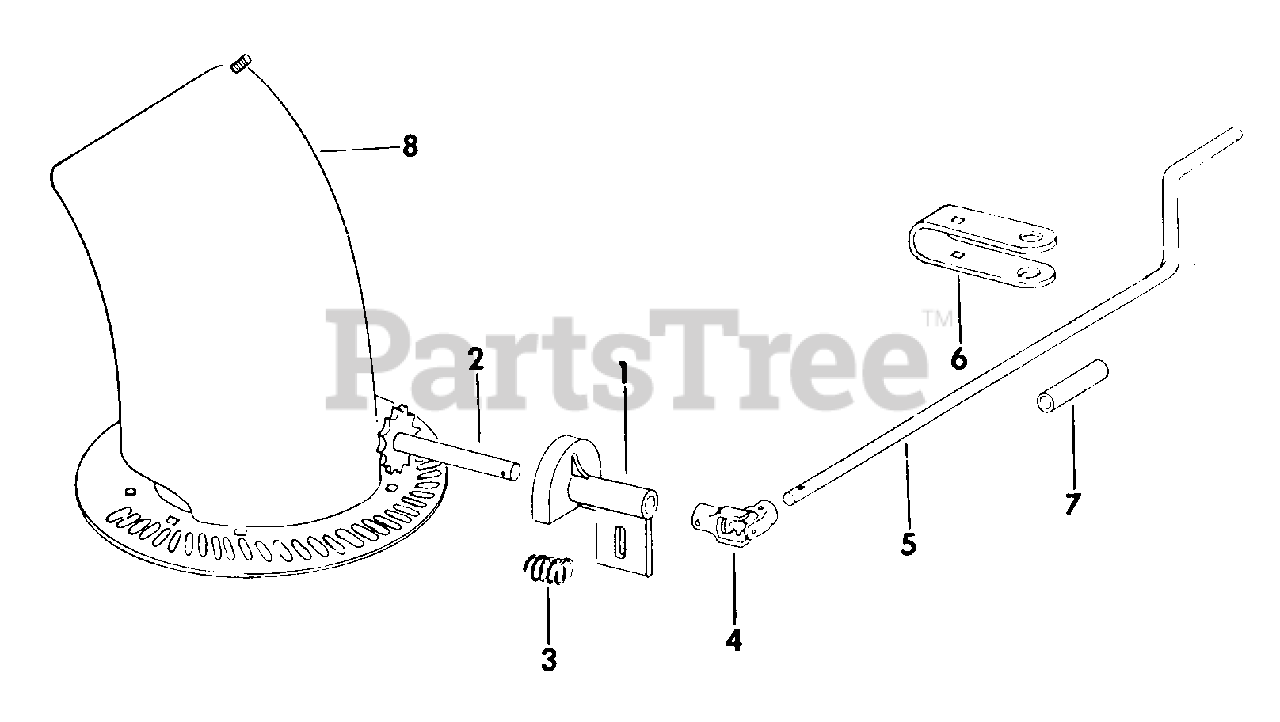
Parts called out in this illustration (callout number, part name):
1	SUPPORT, BRG
2	SPROCKET 12 TEETH
4	UNIVERSAL JOINT
5	HANDLE, CHUTE CONTROL
6	BRACKET, CHUTE CONTROL
7	SLEEVE, CONTROL HANDLE
8	CHUTE, CONTROL
